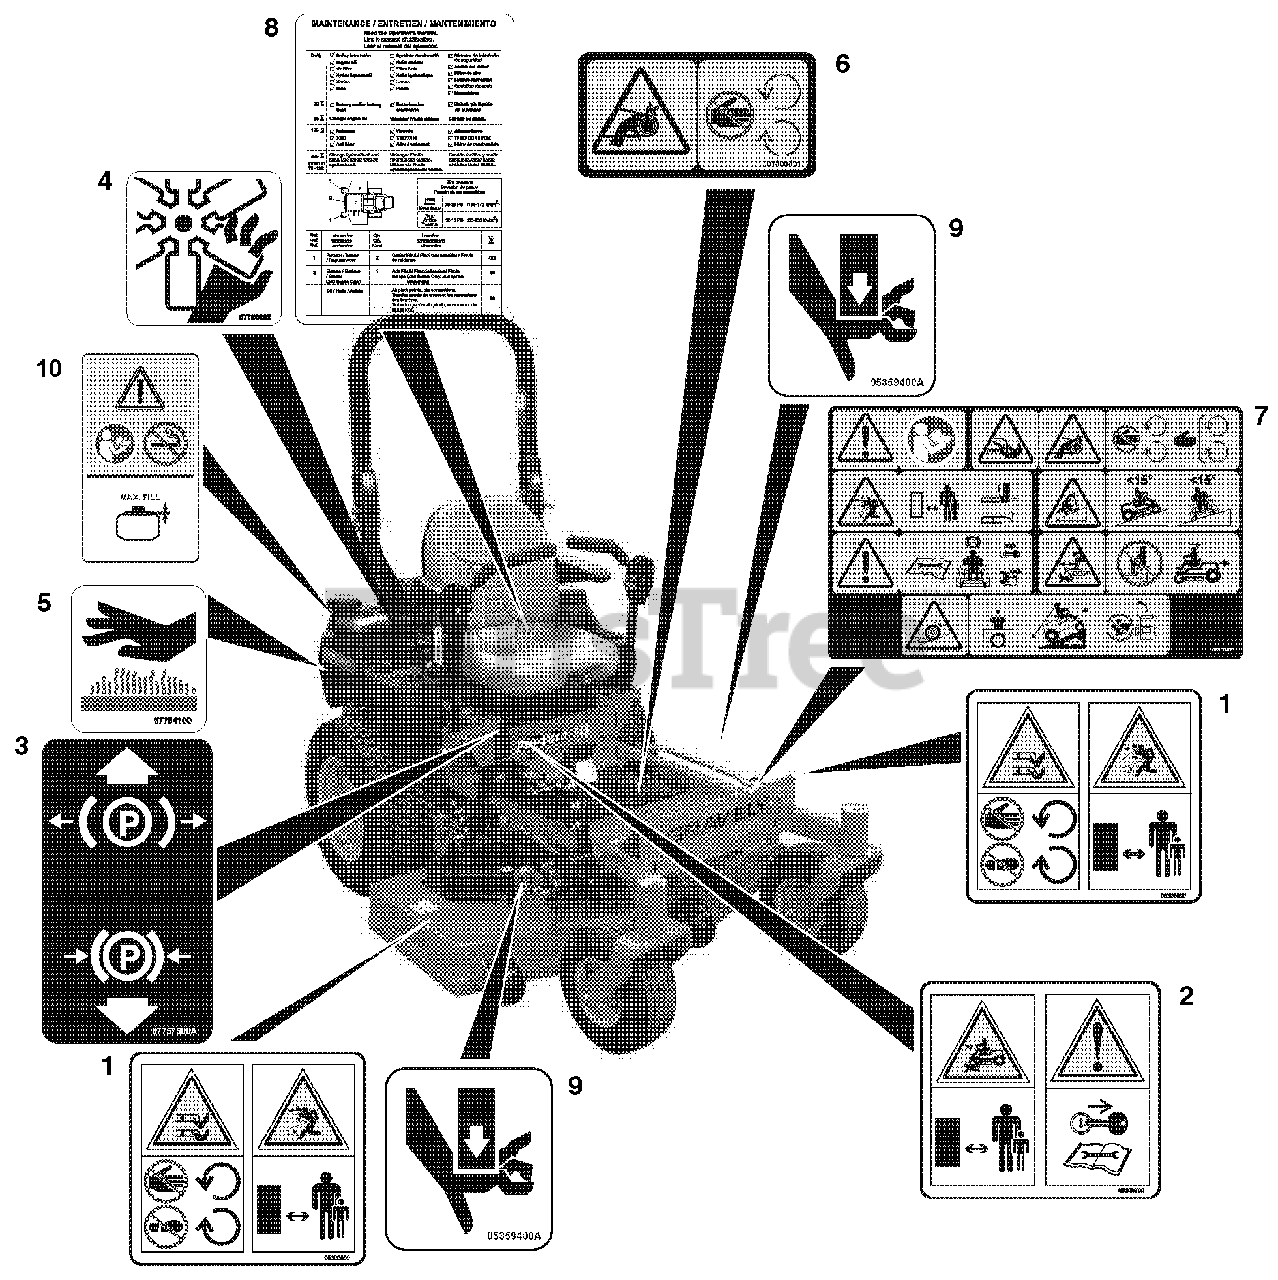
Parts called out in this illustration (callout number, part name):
1	Decal, CE Deck
2	Decal, CE Caution
3	Decal, Parking Brake Lever
4	Decal, Danger Fan
5	Decal, Hot Surface
6	Decal, Safety Guarding
7	Decal, Main Safety Commercial
8	Decal, Maintenance Instructions
9	Decal, Pinch Point
10	Decal, Fuel Warning
